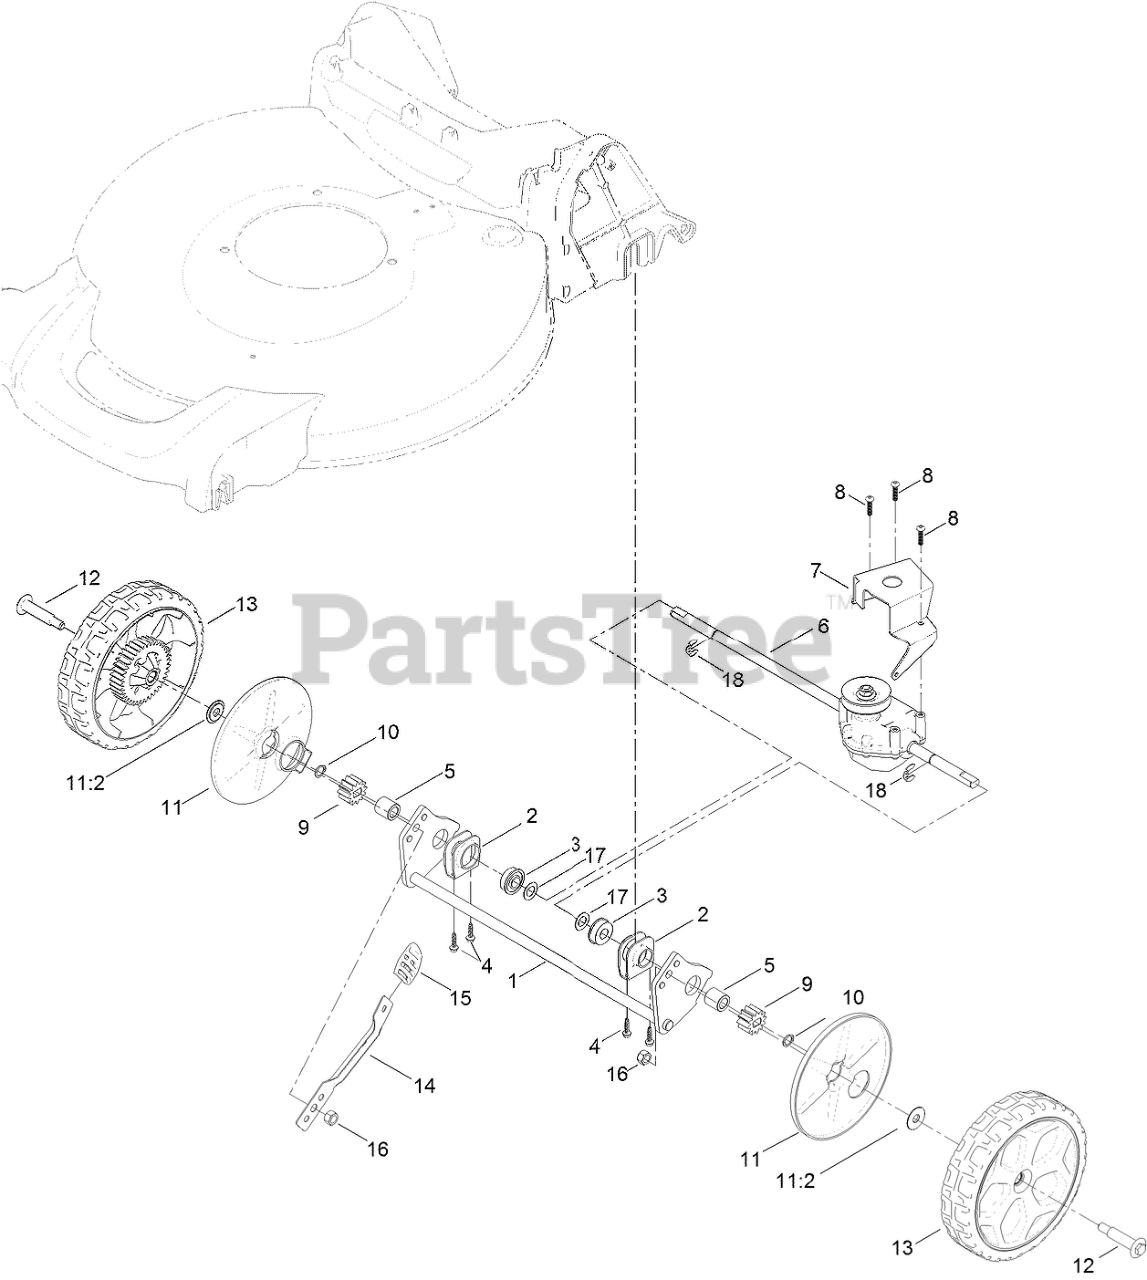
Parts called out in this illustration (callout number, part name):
1	AXLE-REAR
2	RETAINER-BEARING
3	BEARING-BALL
4	SCREW-HWH
5	BUSHING-SLEEVE
6	TRANSMISSION
7	BRACKET-TRANSMISSION
8	SCREW-PLASTITE
9	GEAR-PINION
10	RING-RETAINING
11	WHEEL COVER ASM
11:2	WASHER-STEPPED
12	BOLT-SHOULDER
13	8 INCH WHEEL GEAR ASM
14	ARM-SPRING
15	KNOB-LEVER, HOC
16	NUT-HEX
17	WASHER-PLAIN
18	RING-RETAINING,CLIP
